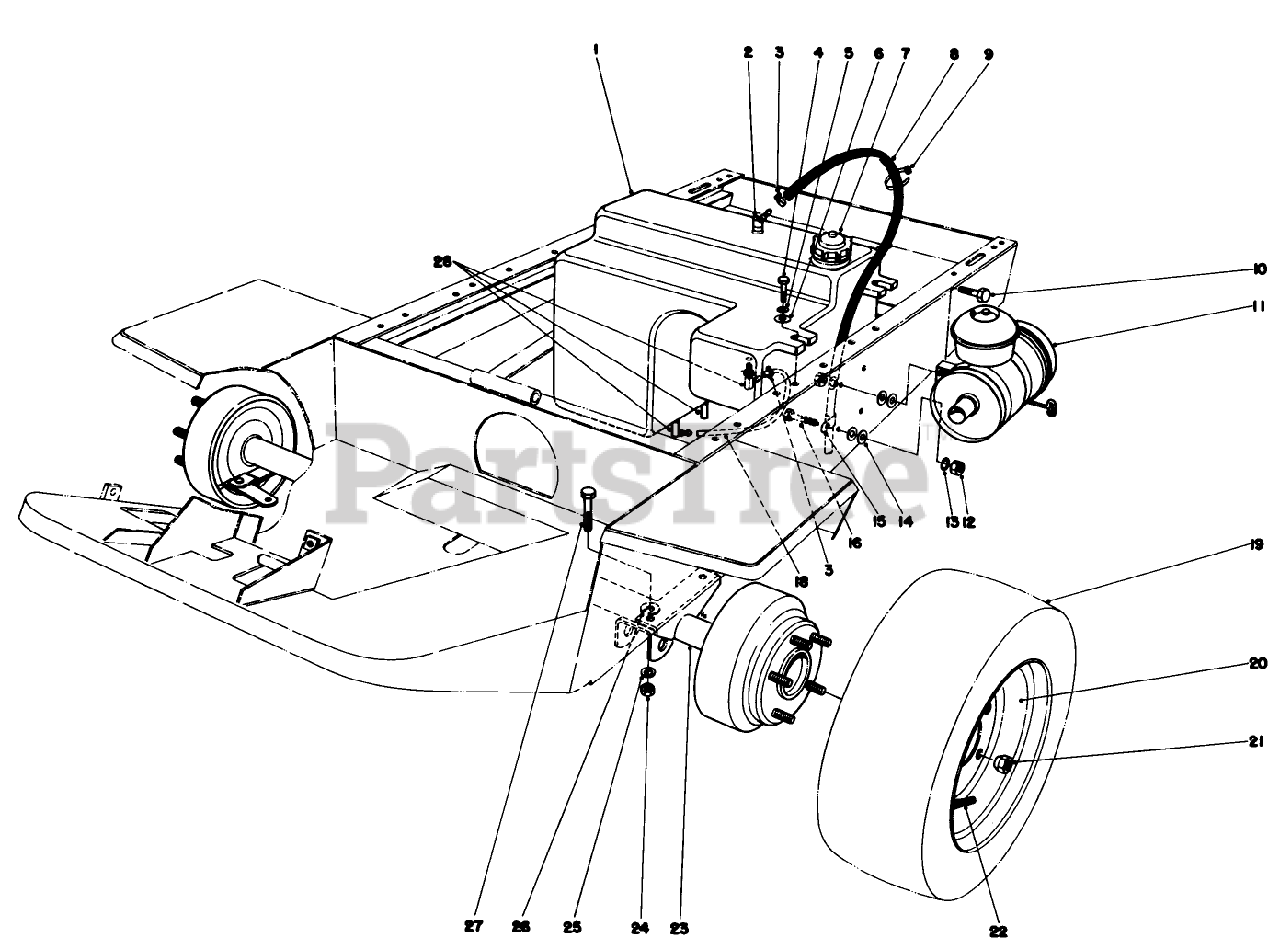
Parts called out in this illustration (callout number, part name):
3	CLAMP-HOSE
4	SCREW-HH
5	WASHER-LOCK
6	WASHER
10	SCREW-HH
11	AIR CLEANER ASM SERV
12	NUT-HEX
13	Lockwasher
14	WASHER-PLAIN
15	CLAMP-R
16	SCREW-HH
20	WHEEL ASM
21	NUT-WHEEL
24	NUT-HEX
25	WASHER-LOCK
26	SPECIAL WASHER
27	SCREW-HH
